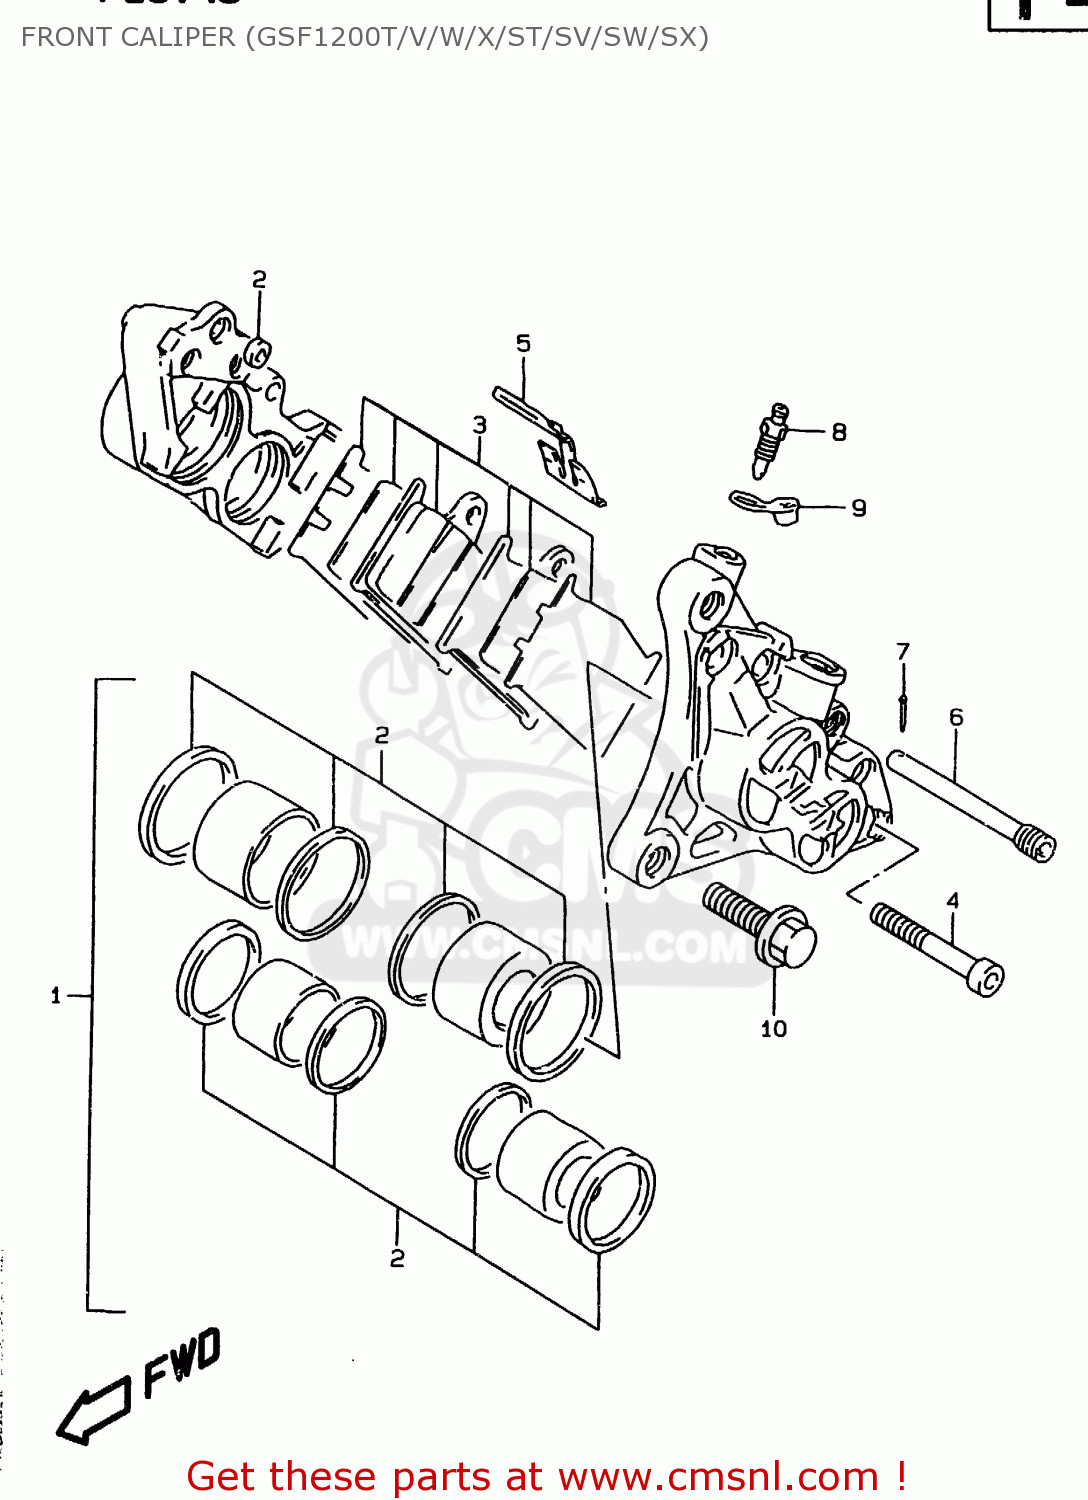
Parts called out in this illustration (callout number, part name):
1	PISTON SET
2	SEAL SET,PISTON
3	PAD & SHIM SET (NAS)
4	BOLT
5	SPRING
6	PIN,HANGER
7	PIN 16X20
8	BLEEDER
9	CAP,BLEEDER
10	BOLT
